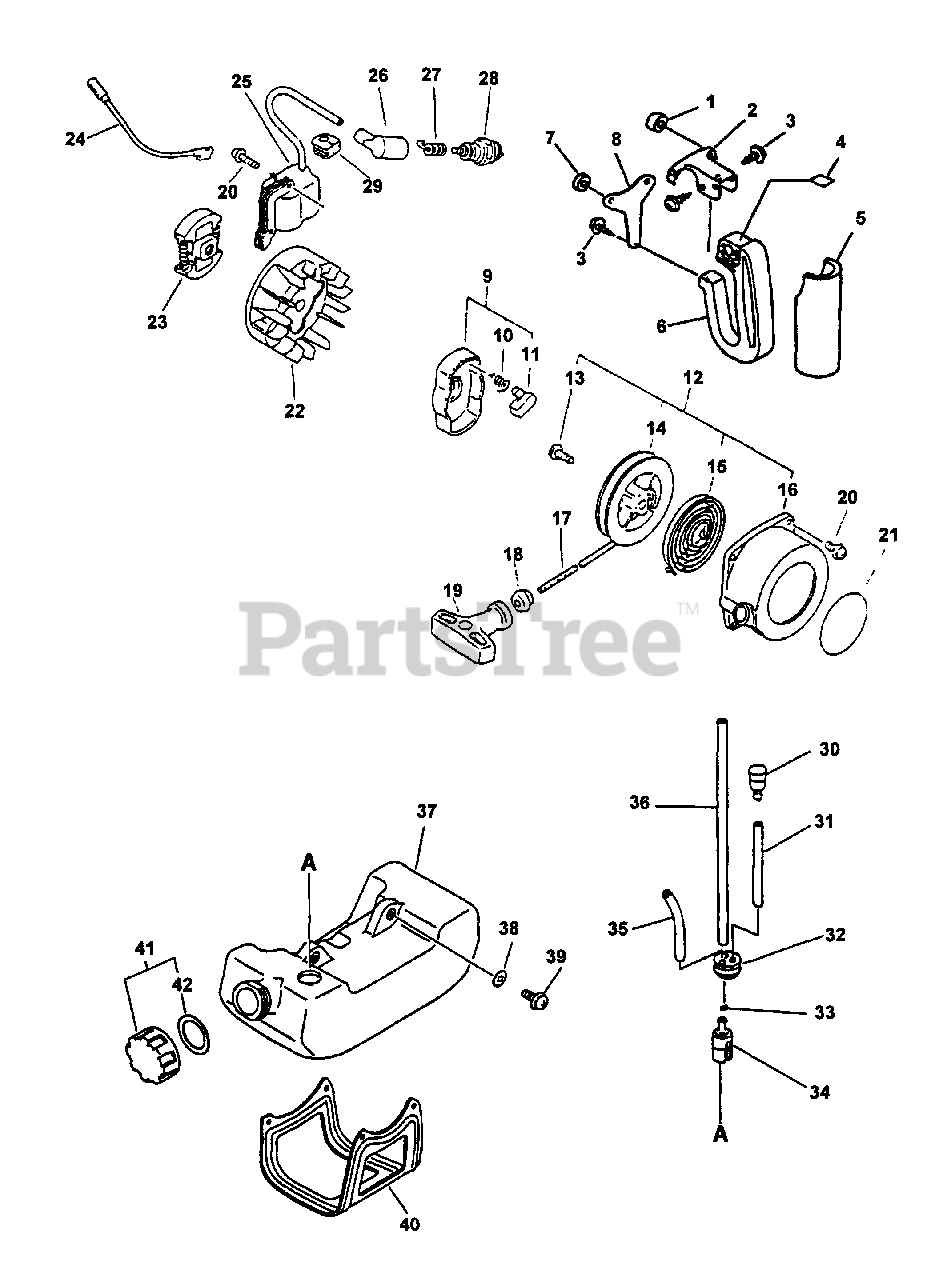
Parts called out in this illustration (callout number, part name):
2	BRACKET, HANDLE
3	SCREW - 5X14
4	LABEL - HOT SURFACE
5	GRIP, HANDLE
6	HANDLE - REAR
8	BRACKET, HANDLE
9	STARTER PAWL ASSY
10	SPRING, RETURN
11	PAWL, STARTER - BLACK
12	STARTER ASSY
14	REEL, ROPE
15	SPRING, REWIND
16	CASE, STARTER
17	ROPE, STARTER - 3X890
18	GUIDE, ROPE
19	GRIP, STARTER
20	SCREW - 4X22
21	LABEL - ECHO
22	FLYWHEEL
23	CLUTCH ASSY
24	LEAD - GROUND
25	COIL, IGNITION
26	CAP, SPARK PLUG
27	TERMINAL, SPARK PLUG CAP
28	SPARK PLUG -- BPM-7Y
30	VENT, FUEL TANK
31	PIPE - 3X5X70 -- BLACK
32	GROMMET
33	CLIP - 6
34	FILTER, FUEL
35	PIPE - 3X6X90 -- CLEAR
36	PIPE - 3X5X180 -- BLACK
37	FUEL TANK ASSY
38	WASHER - 5
39	SCREW - 5X16
40	GUARD, FUEL TANK
41	CAP ASSY
42	GASKET, CAP
